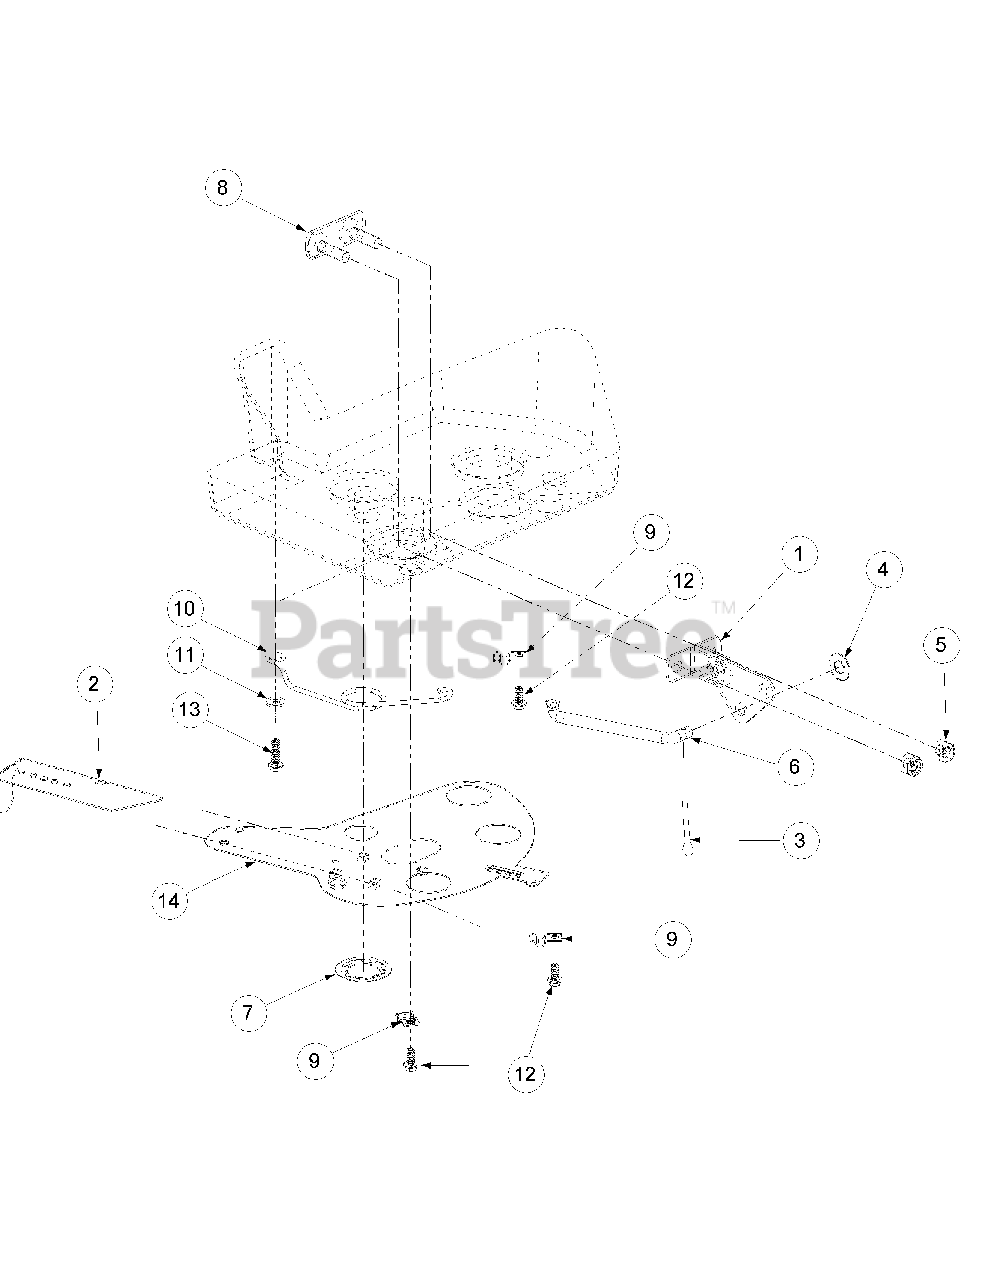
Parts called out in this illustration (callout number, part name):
1	Pivot Lever Assembly
2	Slide Lever
3	Cotter Pin, 3/32 x 1/2 Lg, SS
4	Flat Washer, 1/4"
5	Nylock Nut, 1/4-20
6	Pivot Lever Rod
7	Spring Clip
8	Two Hole Weldment Plate
9	Plate Shut-off Clip
10	Plate Shut-off Spring
11	Flat Washer
12	Index Washer Hex Screw, 8 x 3/8
13	Index Washer Hex Screw, 8 x 5/8
14	Shut-off Plate
